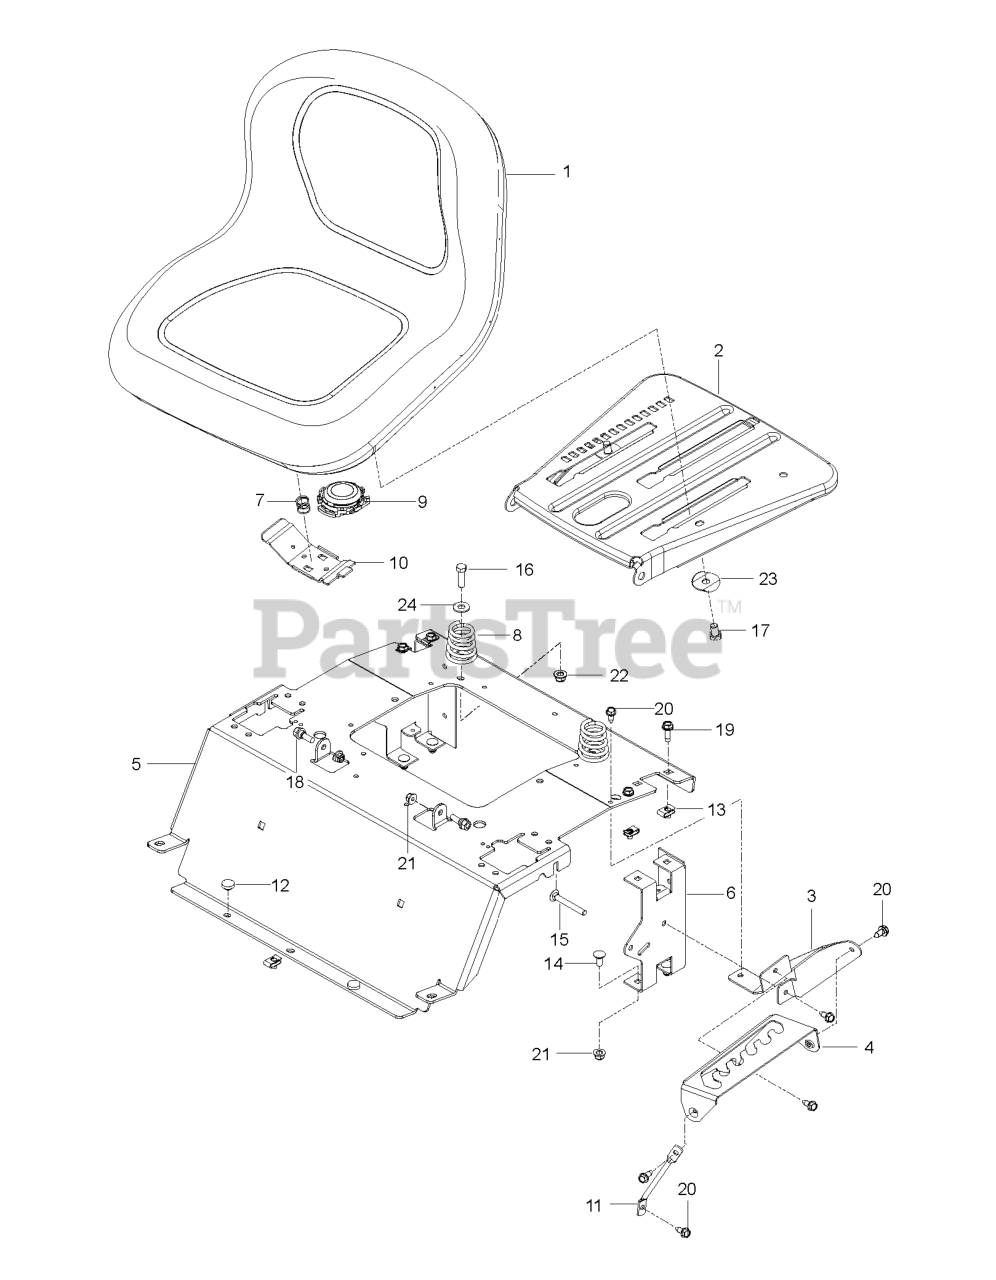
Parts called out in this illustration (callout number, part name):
1	SEAT.TH150.MS498.GRY.HUSQ.TEX
2	PLATE.PNT.SEAT.SLIDE.3PT.EDIP
3	PLATE.SUPPORT.DECK.LIFT.X431
4	PLATE.DECK.LIFT.X431
5	PLATE.SUPPORT.SEAT.RZ.ORANGE
6	SUPPORT REAR SEAT BLACK
7	SPRING.LATCH.SEAT.TEX
8	SPRING.COMPRESS.SEAT.TAPERED
9	SWITCH.SEAT.DELTA.OPC.
10	HANDLE.SLIDE.SEAT.TEX.BLACK
11	SUPPORT.LEG.DECK.LIFT
12	GROMMET.BUMPER
13	U-CLIP 5/16-18 NUT RETAINER
14	RP BOLT 5/16-18 X3/4 ZN/YEL GR
15	RHSNB 5/16-18 X 2-1/2 GR5 ZD
16	BOLT
17	HCS 3/8-16 X 5/8 GR 5 ZD
18	BOLT, SHOULDER
19	SCREW.THDROL.5/16-18X3/4.TTY
20	BOLT.5/16HEX.WHS.HD
21	5/16-18 NYLOC FLANGE NUT
22	NUT 3/8-16 HEX FLG NYLOC ZD
23	WASHER.WINGED.3/8ID.1.5OD
24	RP WASHER 3/8 FLAT
